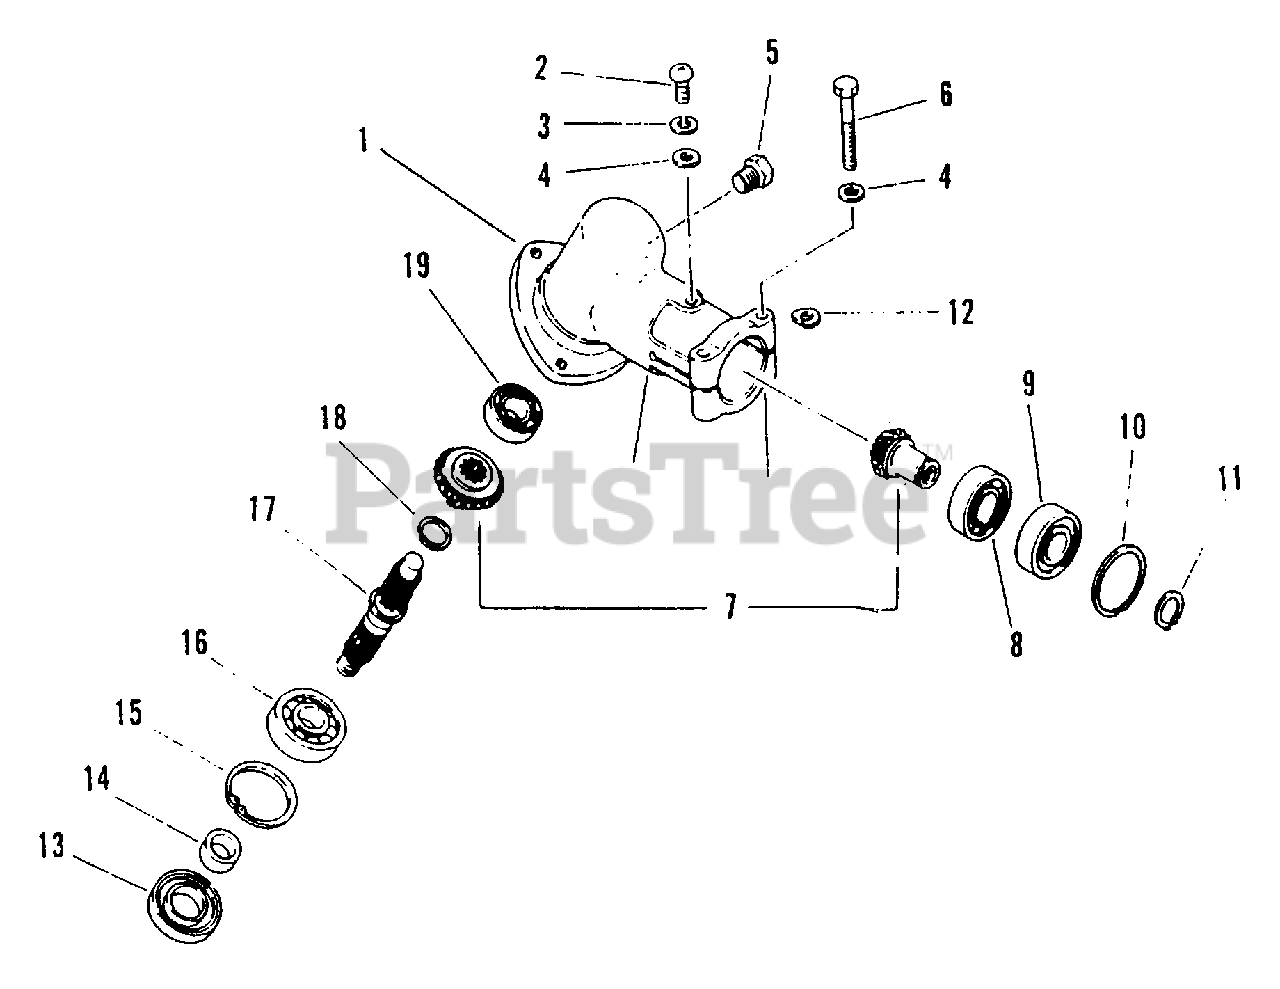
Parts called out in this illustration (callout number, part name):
1	CASE, GEAR
2	SCREW - 5X10
3	LOCKWASHER - 5
4	WASHER - 5
5	BOLT - 8X8
6	BOLT - 5X35
7	GEAR SET - BEVEL
8	BEARING, BALL - 6900
9	BEARING, BALL - 6900Z
10	RING, RETAINING - 22
11	RING, RETAINING - 12
13	SEAL, OIL
15	RING, RETAINING - 32
16	BEARING, BALL - 6201
17	GEAR - SHAFT
18	RING, RETAINING - 10
19	BEARING, BALL - 609
